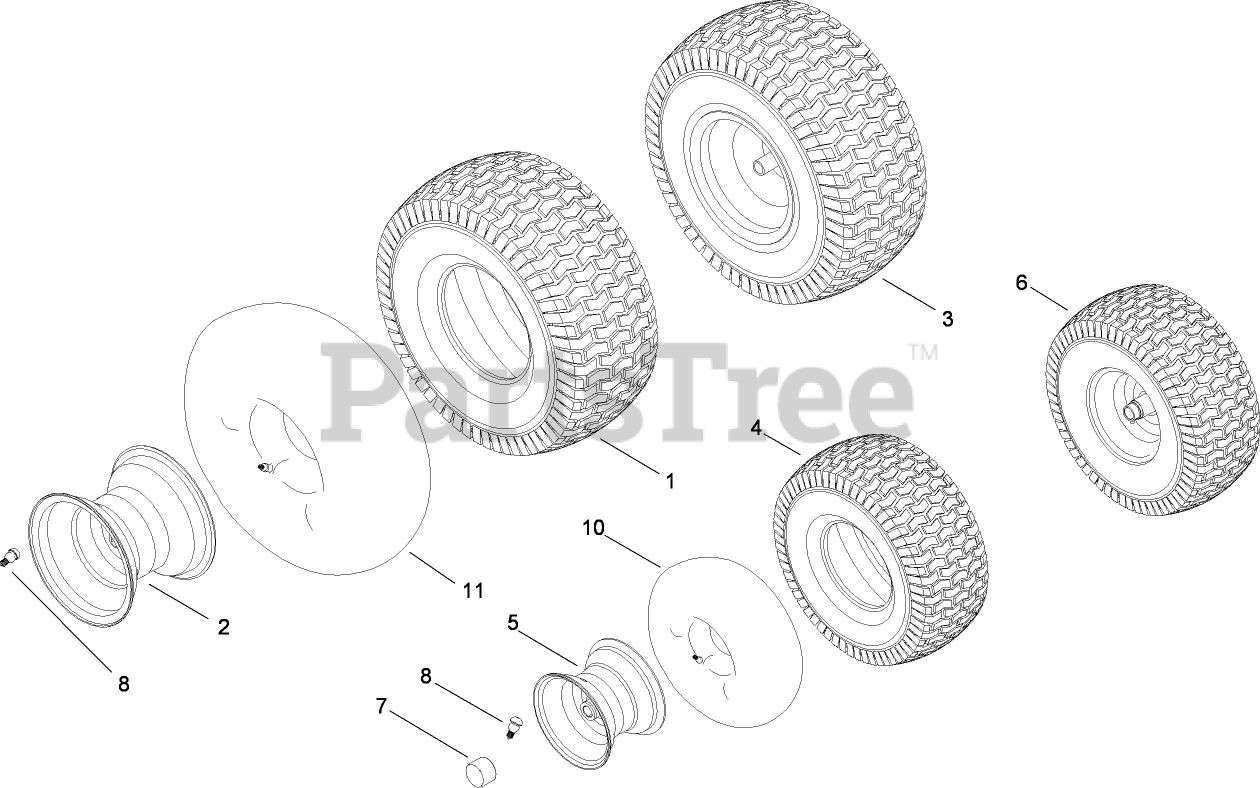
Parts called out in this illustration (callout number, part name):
1	TIRE-MULTI TRAC
2	RIM-WHEEL, REAR
4	TIRE-FRONT
5	RIM-WHEEL, FRONT
7	CAP-HUB
8	VALVE-AIR, TUBELESS
10	TUBE-INNER
11	TUBE-INNER
